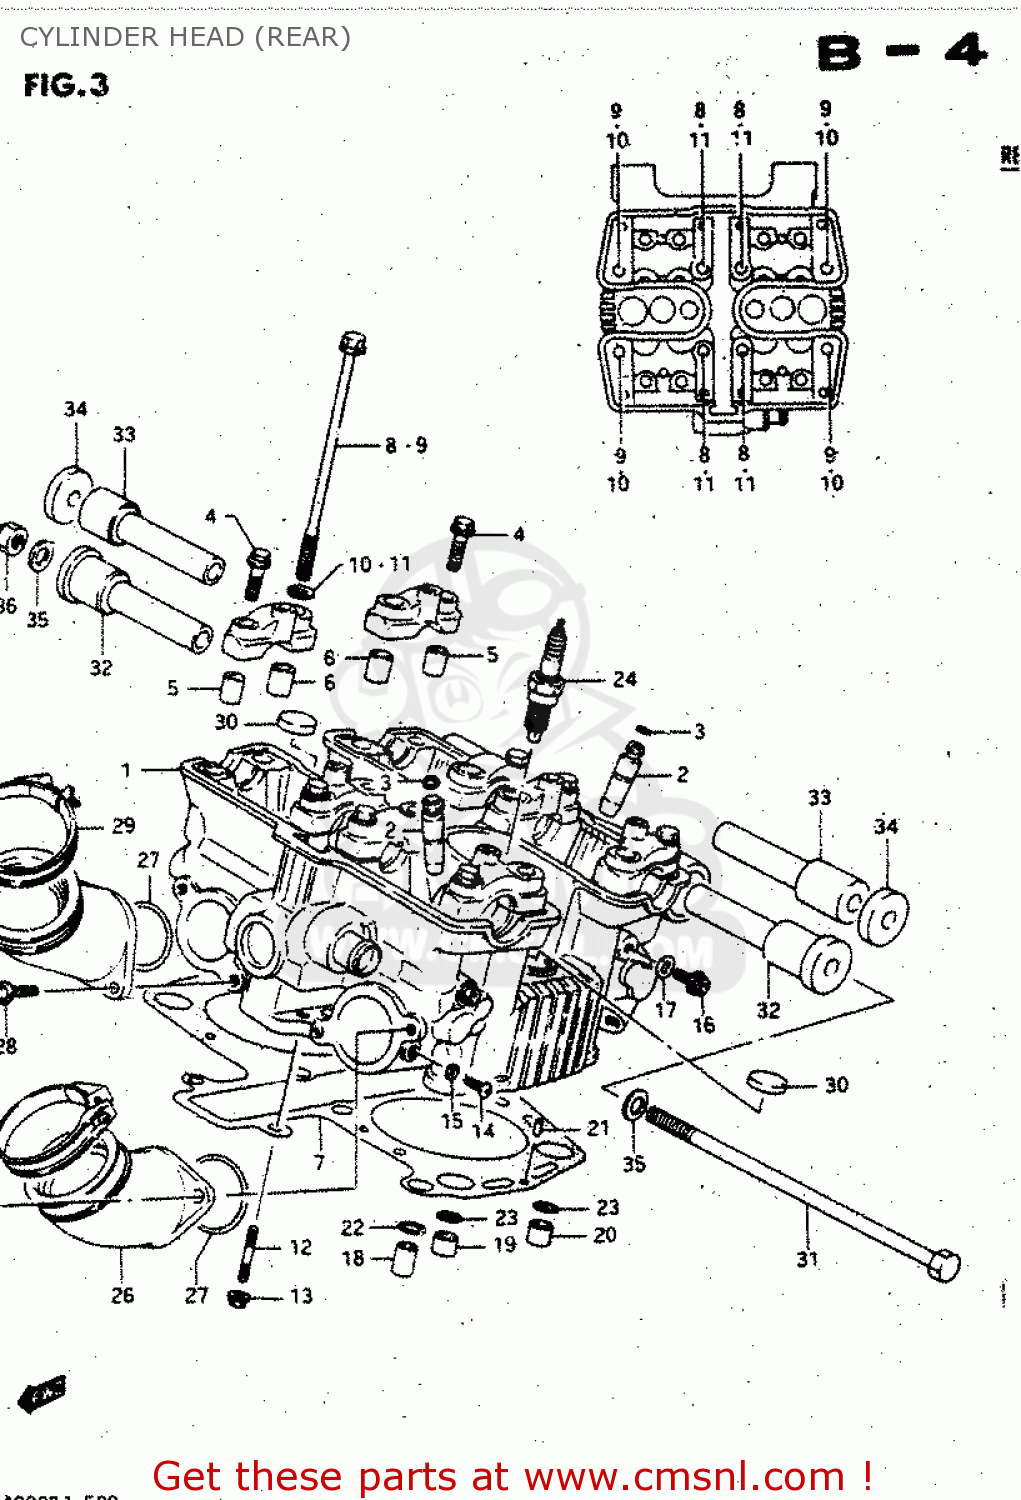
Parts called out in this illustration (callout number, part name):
1	HEAD ASSEMBLY,CYLINDER,REAR
2	GUIDE,VALVE
3	RING,SNAP
4	BOLT
5	PIN (11X20)(SUS)
6	PIN(10.4X13X22)
7	GASKET,CYLINDER HEAD,REAR (MCA)
8	BOLT
9	BOLT
10	WASHER
11	WASHER (10X20X2.3)
12	STUD 6X25
13	NUT 6MM
14	SCREW
15	GASKET(5.3X9.3X1.2) (NAS)
16	BOLT
17	GASKET(6.2X13X1.2) (NAS)
18	PIN
19	PIPE
20	PIN
21	PIN
22	O RING(D:1.9,ID:8.6)
23	O RING(D:1.9,ID:12.6)
24	SPARK PLUG
25	PIPE,INTAKE
26	PIPE,INTAKE
27	O-RING (D:2.4 ID:39.7)
28	BOLT,REAR
29	CLAMP,PIPE
30	PLUG
31	BOLT
32	SPACER,ENGINE MOUNT
33	SPACER,ENGINE MOUNT
34	SPACER,ENGINE MOUNTING NO.2
35	WASHER 10MM
36	NUT
